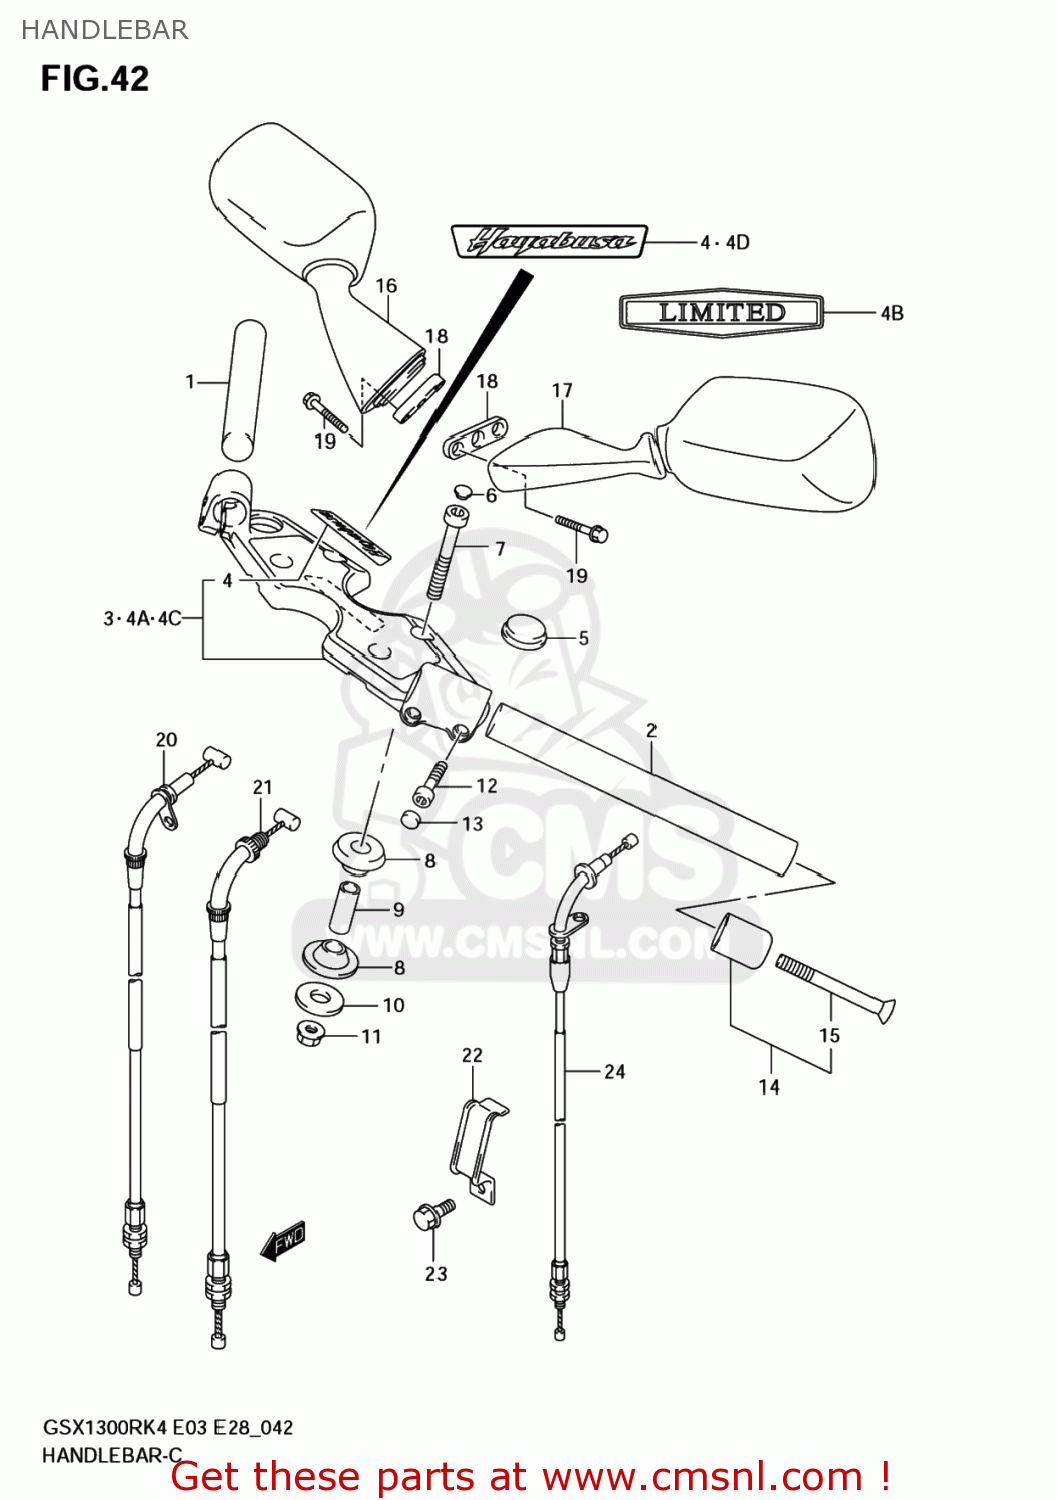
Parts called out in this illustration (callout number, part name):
1	HANDLEBAR,R
2	HANDLEBAR,L
3	HOLDER,HANDLEBAR
4	EMBLEM,HANDLE HOLDER
4A	HOLDER,HANDLEBAR
4B	EMBLEM,LIMITED
4C	HOLDER,HANDLEBAR
4D	EMBLEM,HANDLE HOLDER
5	CUSHION,HANDLE HOLDER
6	CAP,HANDLE HOLDER BRACKET BOLT
7	BOLT
8	CUSHION,UPR BRACKET
9	SPACER,STEERING STEM HEAD
10	WASHER(10.5X30X3.2)
11	NUT
12	BOLT(6X25)
13	CAP(OD:10)
14	BALANCER SET,HANDLEBAR
15	SCREW
16	MIRROR ASSY,RR VIEW,R
17	MIRROR ASSEMBLY,REAR VIEW
18	CUSHION,RR VIEW MIRRORR
19	BOLT
20	CABLE ASSY,THROTTLE NO.1
21	CABLE ASSY,THROTTLE NO.2
22	GUIDE,CABLE
23	BOLT(5X10)
24	CABLE,STARTER
